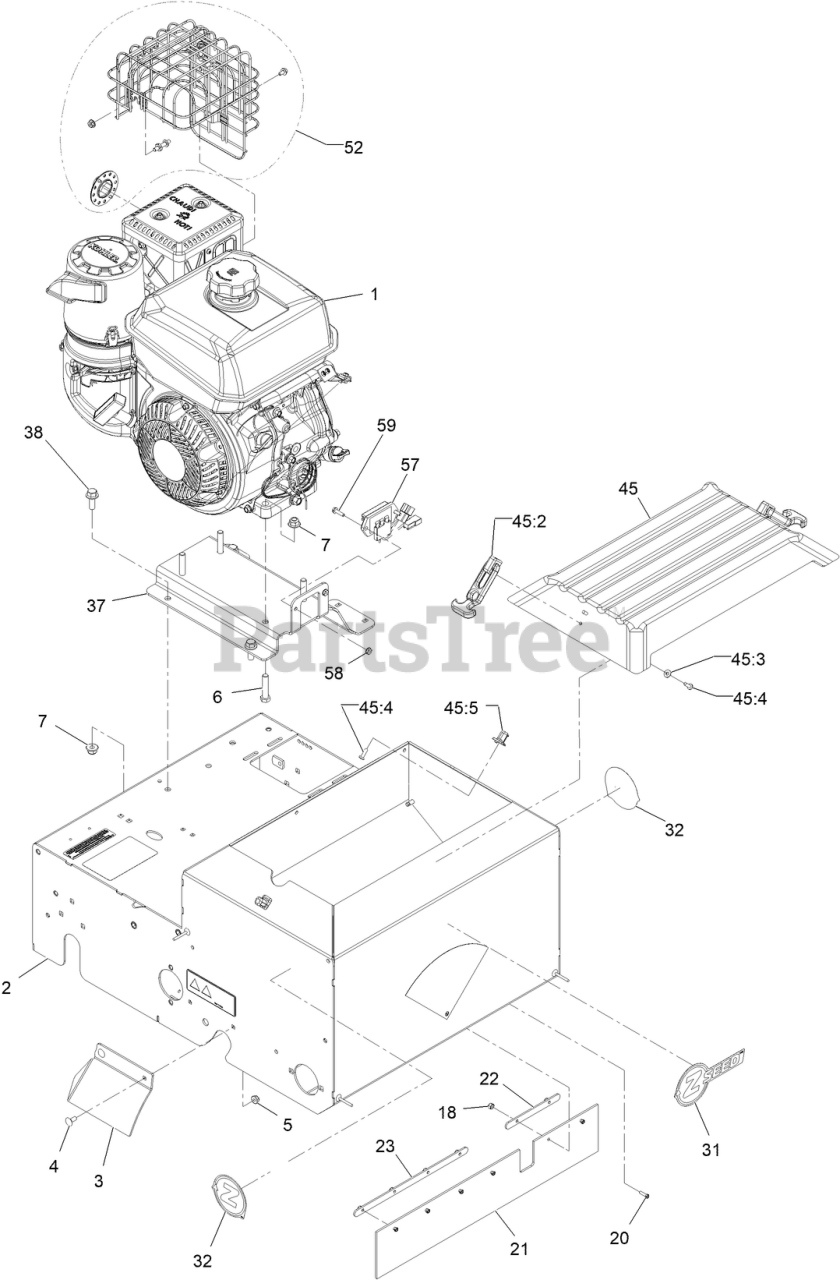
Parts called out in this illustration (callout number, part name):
2	Frame-Service ASM
4	SCREW-CARR
6	SCREW-HH
7	NUT-HF, NI
18	NUT-LOCK
20	SCREW-SHH
21	GUARD-DUST
22	PLATE-RETAINER
23	PLATE-RETAINER
31	DECAL-Z-SEED LOGO
32	Decal-Z-Logo
37	Plate-Engine
38	SCREW-HHF 3/8-16 X 1
45	SEEDER COVER KIT
45:2	LATCH-RUBBER
45:3	WASHER-FLAT
45:4	SCREW-PPH
45:5	LATCH-KEEPER
52	KIT-CH395 MUFFLER GUARD
57	Regulator
58	Nut-Keps
59	SCREW-HWH
